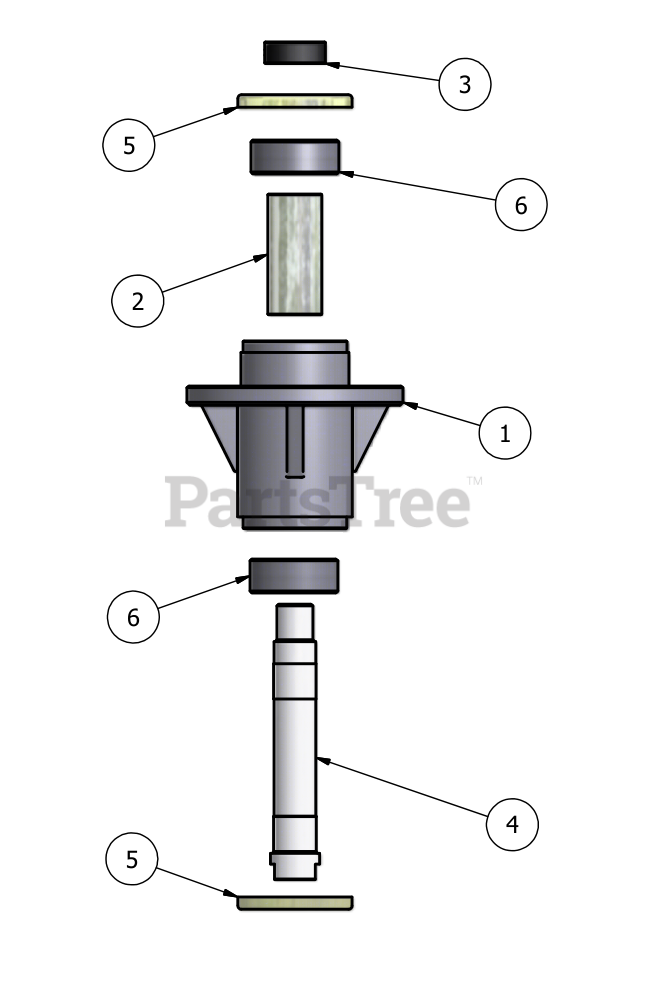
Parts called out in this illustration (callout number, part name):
1	Spindle Housing
2	Spindle Spacer
3	Spindle Coller
5	Bearing Cover
